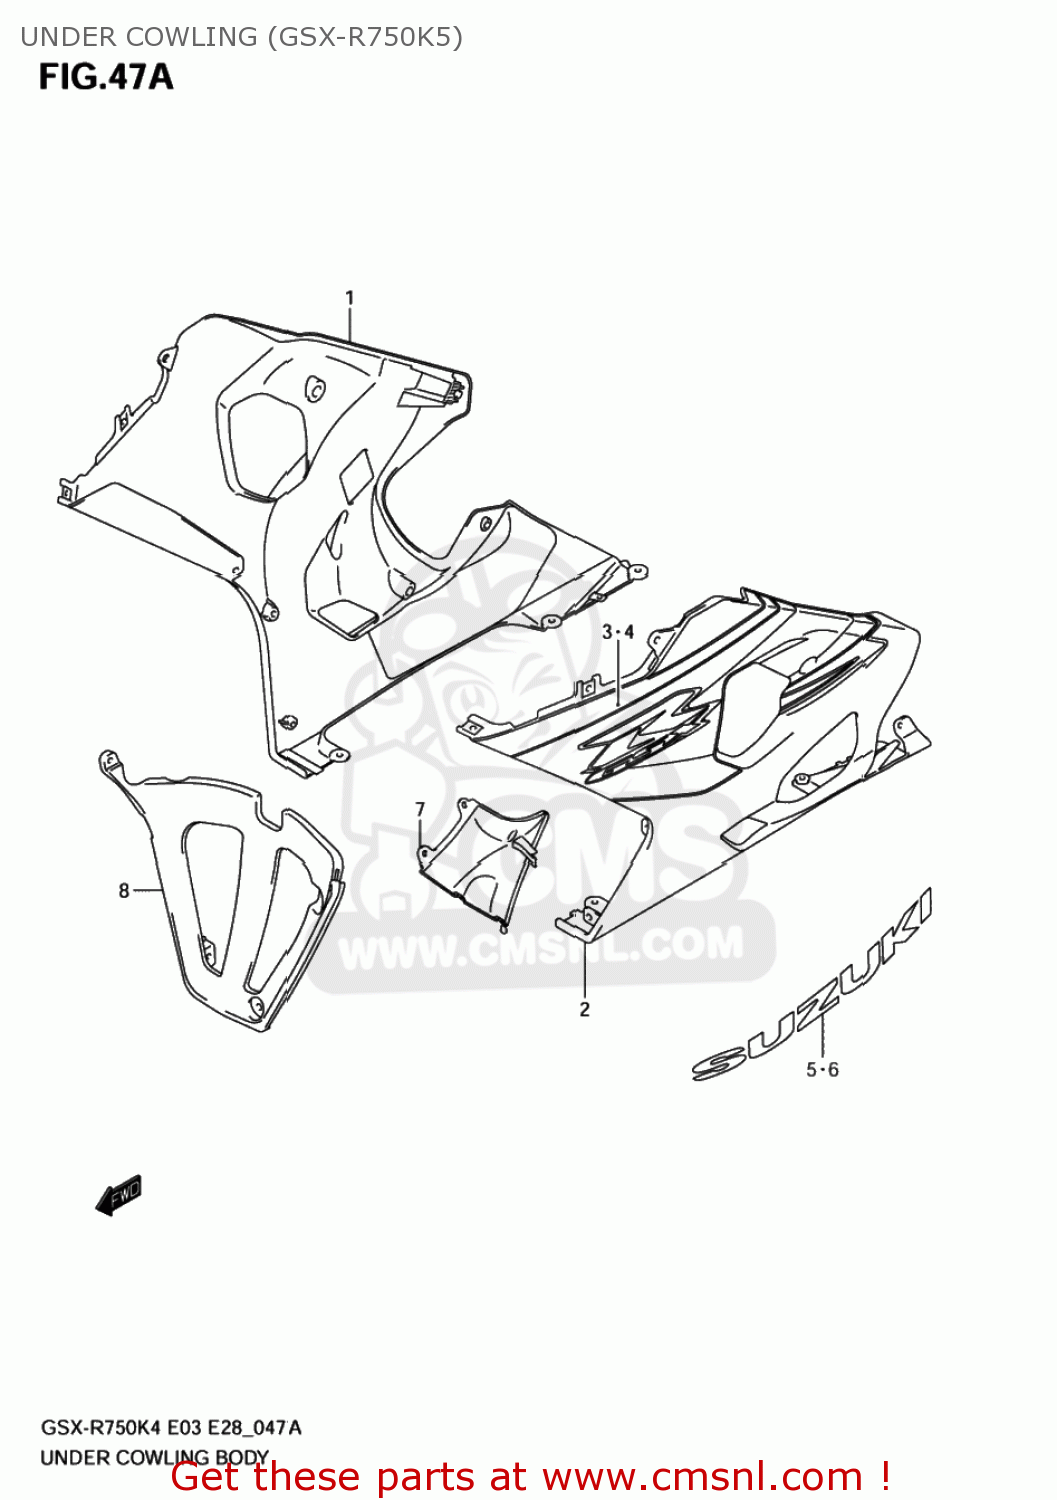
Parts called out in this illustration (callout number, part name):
1	COWLING ASSY,UNDER,R
2	COWLING ASSY,UNDER,L
3	TAPE SET,COWL UNDER,R
4	TAPE SET,COWL UNDER,L
5	EMBLEM,R
6	EMBLEM,L
7	COWLING,UNDER INNER,L
8	COWLING,UNDER CTR
